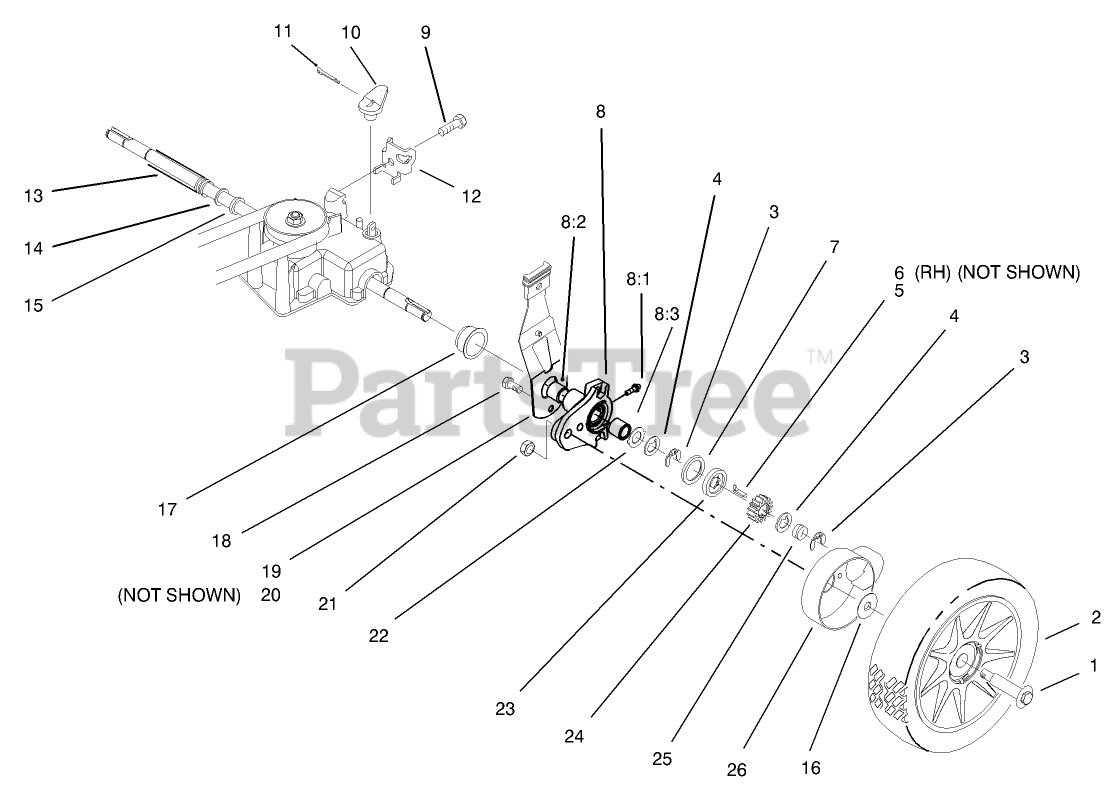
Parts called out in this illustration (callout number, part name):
1	BOLT-SHOULDER
2	WHEEL AND GEAR ASM
2:3	8" Wheel Assembly
2:3:1	BUSHING
3	RING-CLIP, LOCKING
4	WASHER-THRUST, KEYED
5	KEY-ROCKING, LH
6	KEY-ROCKING, RH
7	RING-FRICTION
8	REAR HEIGHT ADJUSTMENT ARM ASM
8:2	BUSHING
8:3	BUSHING
8:4	FITTING-GREASE
9	SCREW-HWHTF
10	LEVER-SHIFT
11	PIN-COTTER
12	CLAMP-CABLE
13	COVER-SHAFT, DRIVE
14	WASHER
15	WASHER
16	WASHER-STEPPED
17	RING-ISOLATOR
18	SCREW-HWH
19	LH REAR SPRING ARM ASM
20	RH REAR SPRING ARM ASM
22	WASHER-ARM, PIVOT
23	WASHER-CLUTCH
24	GEAR-PINION
25	SPRING-COMPRESSION
26	COVER-WHEEL
